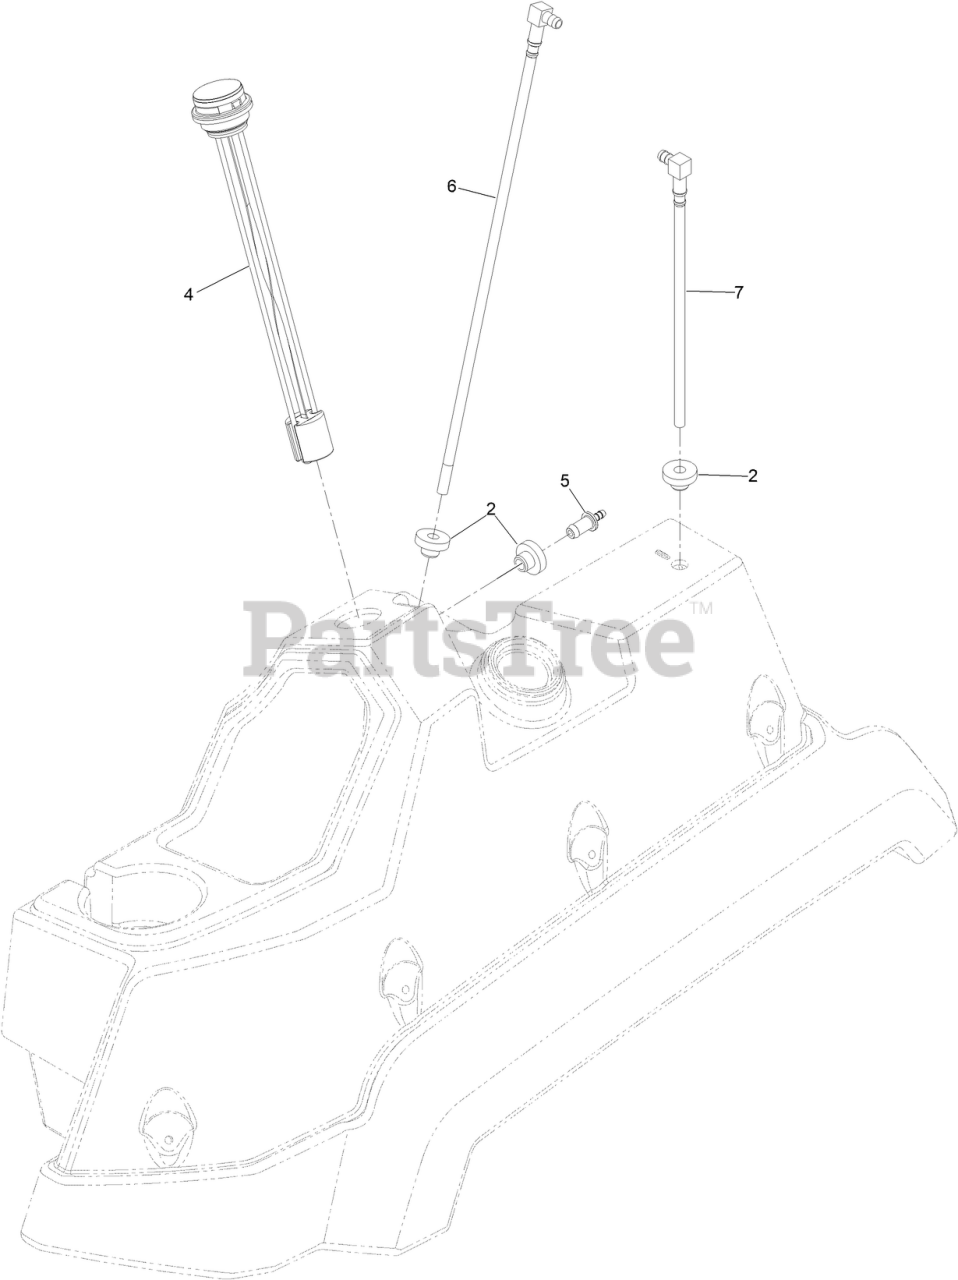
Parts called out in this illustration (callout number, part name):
2	BUSHING
4	GAUGE-FUEL
5	FITTING-ORIFICE, STRAIGHT
6	PICK-UP-FUEL
7	RETURN-FUEL
